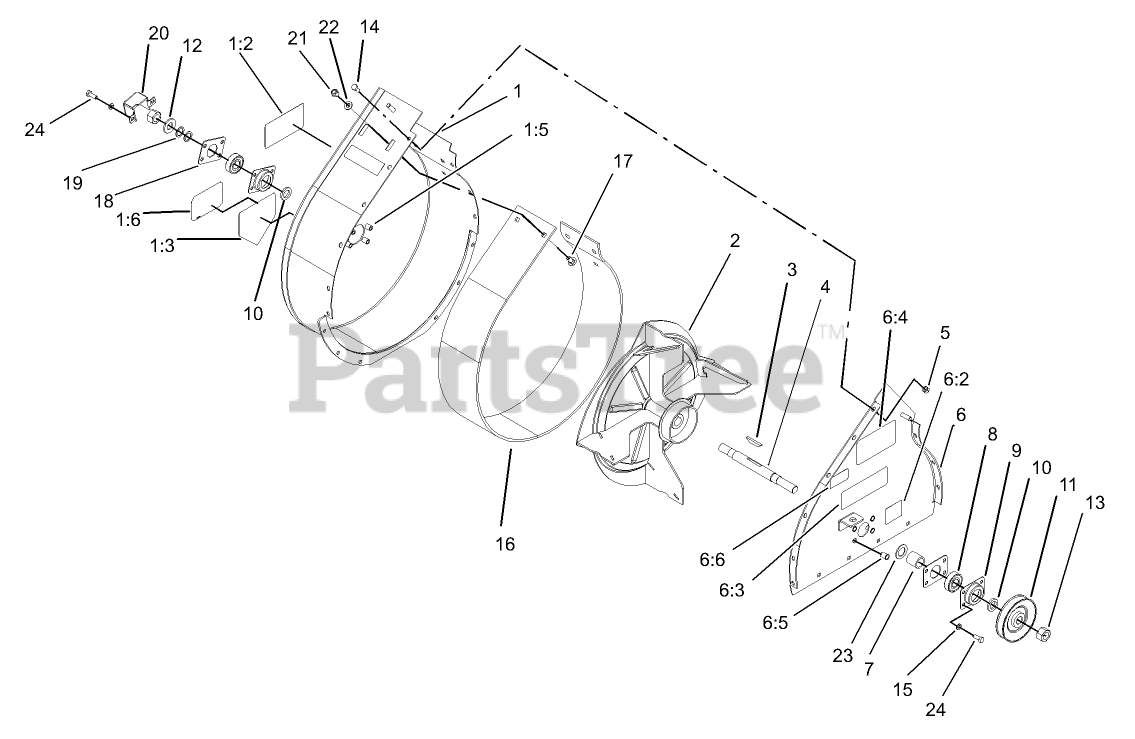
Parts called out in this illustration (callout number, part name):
1	Blower Housing ASM
1:2	DECAL-DANGER
1:3	DECAL-DANGER
1:5	INSERT-NUT
1:6	DECAL
2	IMPELLER ASM
4	Shaft-Blower
5	NUT-LOCK, NI
6	COVER PLATE ASM
6:2	DECAL-WARNING
6:3	DECAL-DANGER
6:4	DECAL-DANGER
6:5	INSERT-NUT
6:6	DECAL-PROTECTION, EAR
7	Spacer
8	BEARING-BALL
9	CUP-BEARING
10	SPACER-BEARING
11	Pulley ASM
12	WASHER-FLAT
13	NUT-HEX
14	SCREW-HH
15	WASHER-LOCK
16	STRIP-WEAR
17	BOLT-CARR
18	PLATE-COVER
19	WASHER-FLAT
20	Cover-Shaft
21	NUT-LOCK, NI
22	WASHER-PLAIN
23	WASHER-THRUST
24	SCREW-HH
